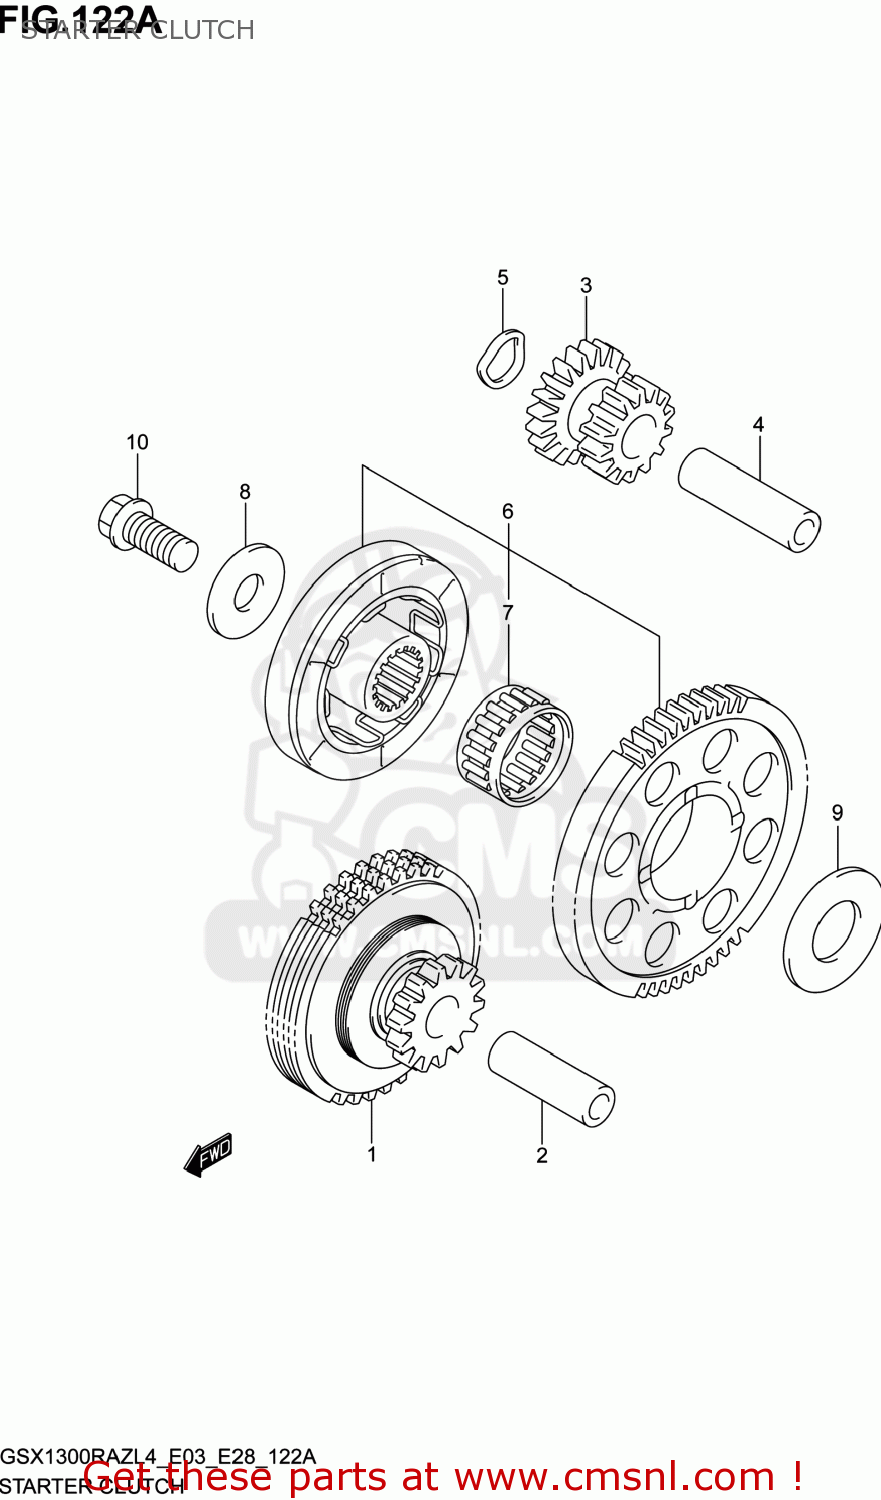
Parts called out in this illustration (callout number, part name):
1	LIMITER ASSY,START ID GR NO.1
2	PIN,STARTER IDLE GEAR NO.1
3	GEAR,STARTER IDLE NO.2
4	PIN ,PISTON
5	WASHER
6	CLUTCH SET,STARTER
7	BEARING(28X34X16.8)
8	WASHER
9	WASHER
10	BOLT(10X23)
